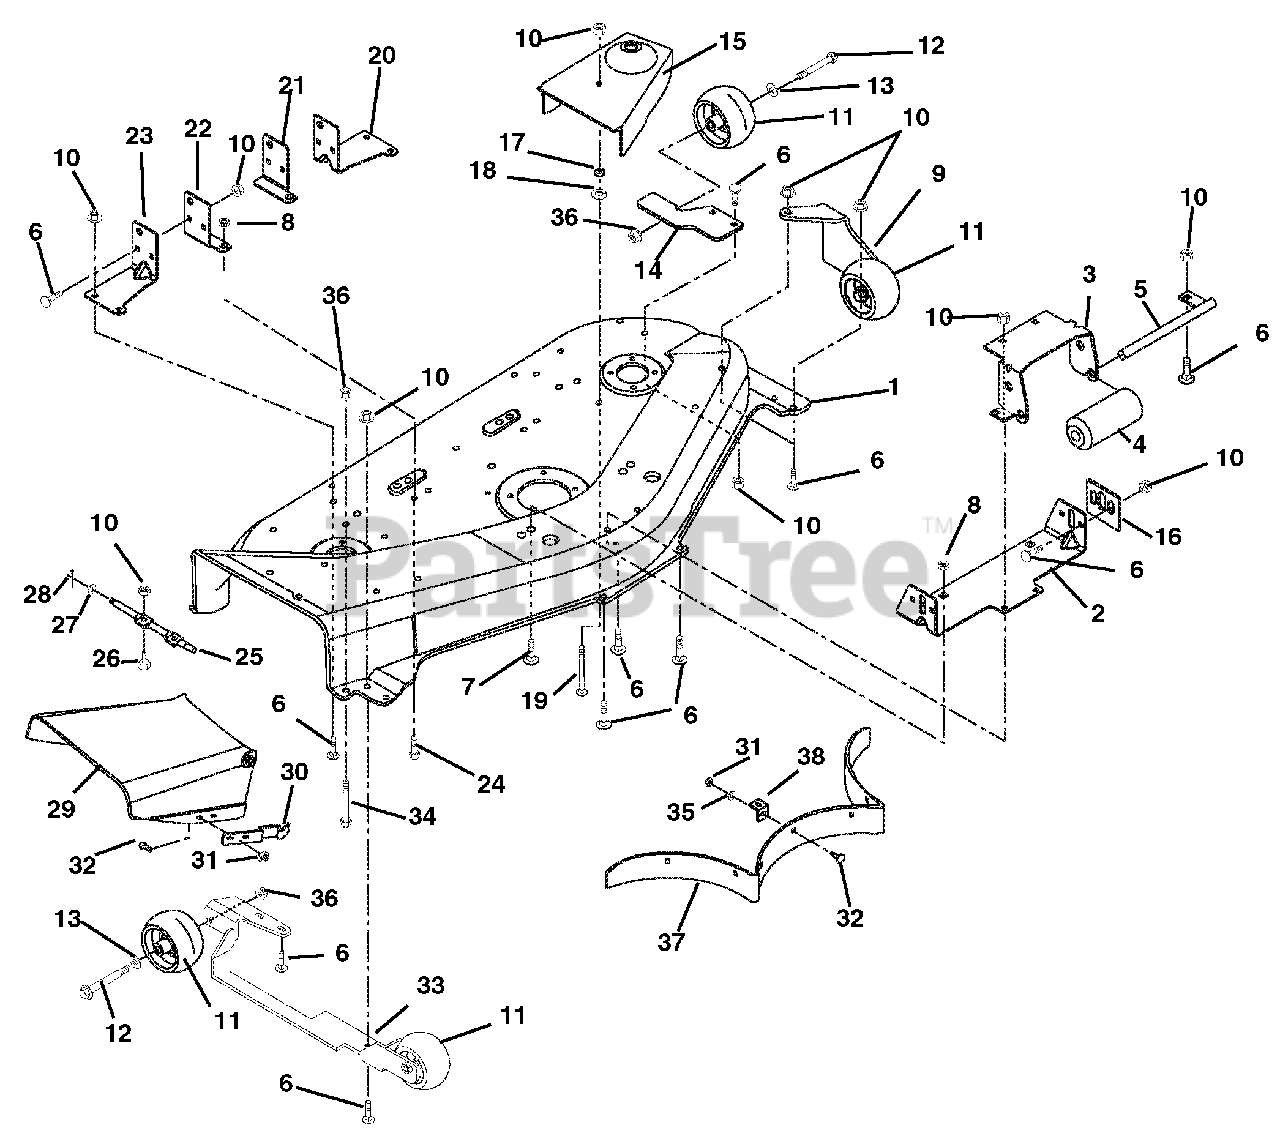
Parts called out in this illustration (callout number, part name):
1	Mower Pan Head w/Decals 48"
2	Front Hanger
3	Bracket, Roller
4	Roller
5	Roller Shaft
6	Bolt-Round Head Square Neck .31-18 x .75 Grade 5
7	Bolt-Round Head Square Neck .50-13 x .75 - Short Neck
8	Nut-Locking-Top-Flange .50-13
9	Bracket-Left Front
10	Nut-Locking-Top-Flange .31-18
11	Wheel 5 x 3
12	Bolt-Shoulder .38-16 x 2.50 Hex Washer Head Grade 5
13	Washer-Flat-Nylon .52 x 1.00 x .08
14	Bracket-Left Rear
15	Belt Cover Right Hand 48"
15	Belt Cover Left Hand 48"
16	Mower Adjustment Tab
17	Nut-Hex .31-18
18	Washer-Locking .31 x .097 Heavy
19	Bolt-Round Head Square Neck .31-18 x 3.25
20	Left Hand Rear Hanger
21	Left Hand Rear Hanger Support
22	Right Hand Rear Hanger Support
23	Right Hand Rear Hanger
24	Bolt-Hex .50-13 x 1.00 Grade 5
25	Hinge Pin
26	Bolt-Hex .31-18 x .75 Grade 5
27	Washer-Flat-Steel .406 x .812 x .065
28	Pin-Cotter .09 x .75
29	Chute Extension
30	Flat Spring
31	Nut-Locking-Center .25-20
32	Bolt-Round Head Square Neck .25-20 x .50 Grade 5
33	Mount- Roller
34	Bolt-Round Head Square Neck .38-16 x 2.50 Grade 5
35	Washer-Flat-Steel .281 x .620 x .065
36	Nut-Locking-Top-Flange .38-16
37	Baffle
38	Baffle Tab
